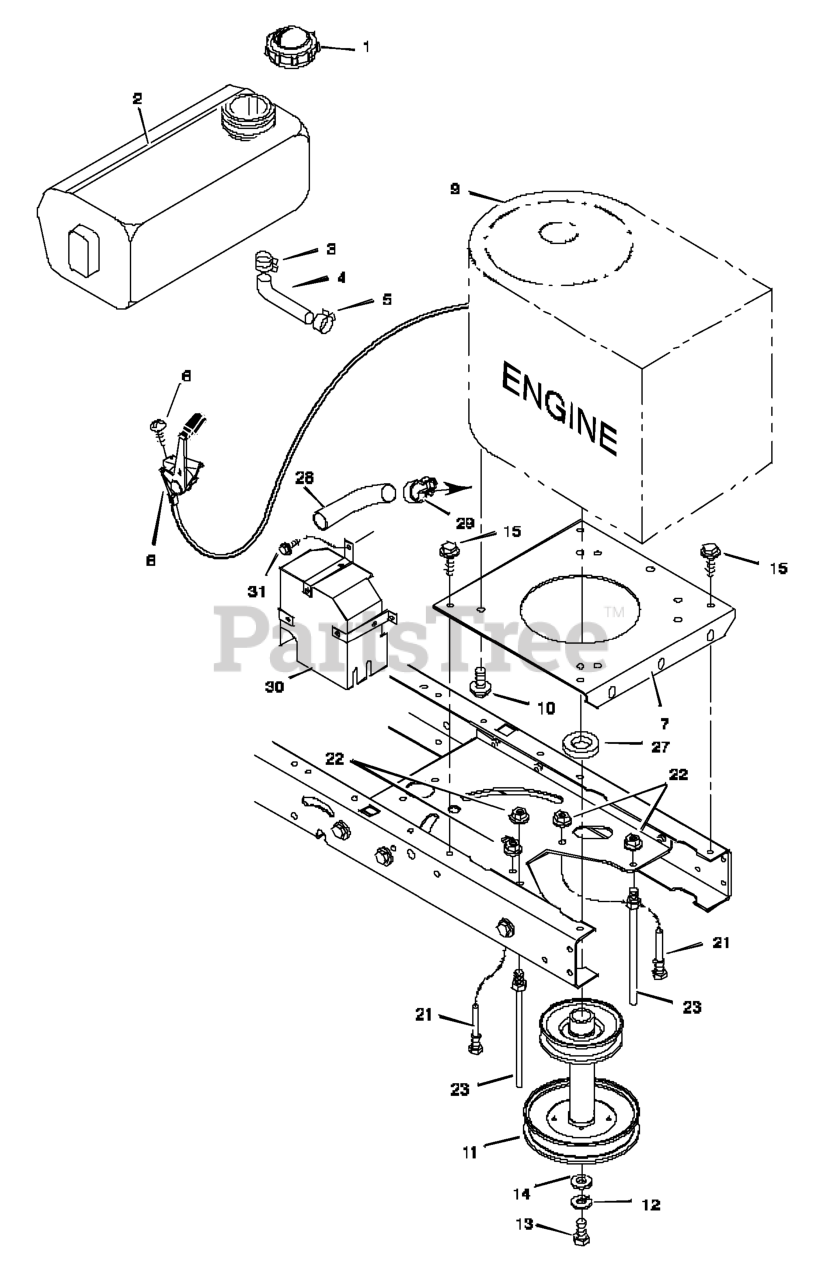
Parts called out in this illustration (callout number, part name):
1	Fuel Cap
2	Fuel Tank
3	Hose Clamp
4	Fuel Line
5	Hose Clamp
7	Plate, Engine
8	Throttle Control
9	Engine
10	Bolt, Engine Mount
11	Stack Pulley Assembly
12	Lockwasher
13	Bolt, Hex
21	Guide, Belt
22	Nut, Flange
23	Guide, Belt
28	Pipe, Exhaust
30	Shield, Heat
